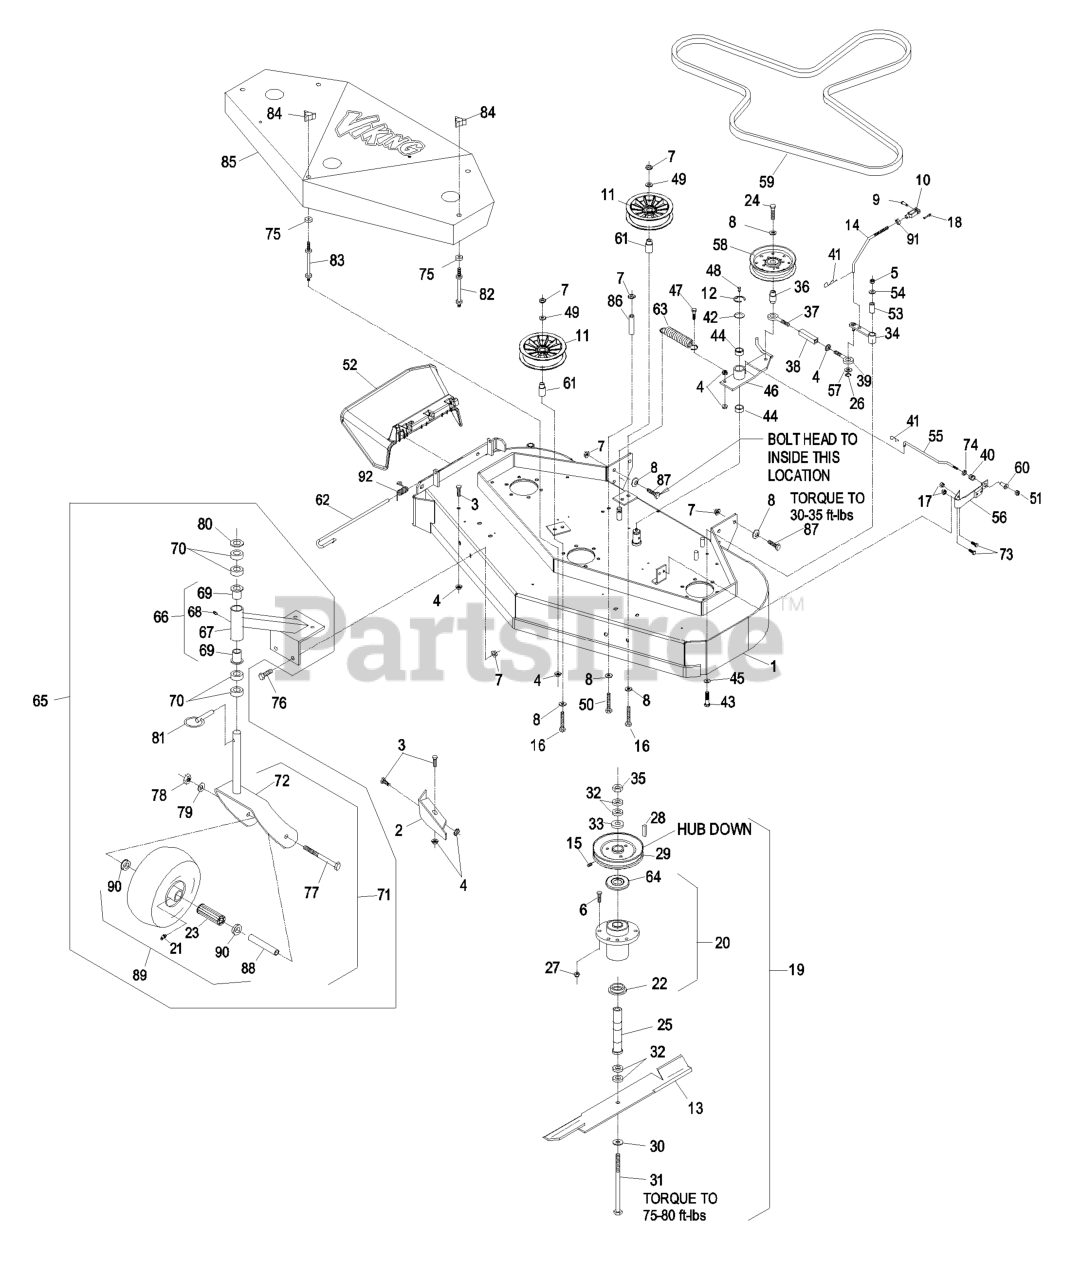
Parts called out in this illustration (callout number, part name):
1	DECK-SERVICE, 48
2	BAFFLE-DOGLEG
3	SCREW-HH
5	NUT-LOCK, NI
6	SCREW-HH
7	NUT-HHF, WHIZ
8	WASHER-BELLEVILLE
9	PIN-CLEVIS
10	YOKE-ADJUSTABLE
11	PULLEY,IDLER 5"
12	RING-RETAINING, EXT
14	ARM-LINKAGE, ASSIST
15	SCREW-SET
16	SCREW-HH
17	NUT-LOCK, NI
18	PIN-COTTER
19	ASM, CUTTER HOUSING OUTER
20	KIT, CUTTER HOUSING
21	FITTING-GREASE
22	SPACER-GUARD, BOTTOM
23	BEARING
24	SCREW-HH
25	TUBE-SPINDLE, SHORT
26	RING-RETAINING, EXT
27	NUT-LOCK, NI
29	SHEAVE
30	WASHER-SPRING
31	SCREW-CAP, HH
33	WASHER-RETAINER, SHEAVE
34	ARM-ASSIST, 32/36
35	NUT-HEX
36	BUSHING-ENGAGEMENT
37	EYEBOLT-THREAD, LH
38	BODY-TURNBUCKLE
39	EYEBOLT-THREAD, RH
40	SPRING-COMPRESSION
41	PIN-COTTER
42	WASHER-SPINDLE
43	SCREW-HH
44	SLEEVE-BEARING
45	WASHER-SPRING
46	IDLER ARM ASM
47	SCREW-HH
48	FITTING-GREASE
49	WASHER-FLAT
50	SCREW-HH
51	NUT-LOCK, NI
52	CHUTE DEFLECTOR XRK M056
53	TUBE-PIVOT
54	WASHER-FLAT
55	ROD-BRAKE
56	PAD AND SPRING ASM
57	WASHER-PLAIN
59	BELT,BLADE 48
60	SPACER-FLANGED
62	PIN-CHUTE
63	SPRING-EXTENSION
64	GUARD-BEARING, TOP
66	ASM,CSTR SUPPORT W/WEIGHT
68	FITTING-GREASE
69	BEARING-FLANGED
70	SPACER-CASTER
71	ASM,CASTER/WHEEL
73	SCREW-HH
74	RING-PUSH ON
76	SCREW-HH
77	SCREW-HH
78	NUT-HH
79	WASHER-LOCK
80	WASHER-FLAT
82	STUD-SHIELD, BELT (SHORT)
83	STUD-SHIELD, BELT (LONG)
84	KNOB-3 PRONG
87	SCREW-HH
89	KIT, SP CASTER WHEEL REPL
90	BUSHING
91	NUT-HEX
92	SPRING, TORSION
